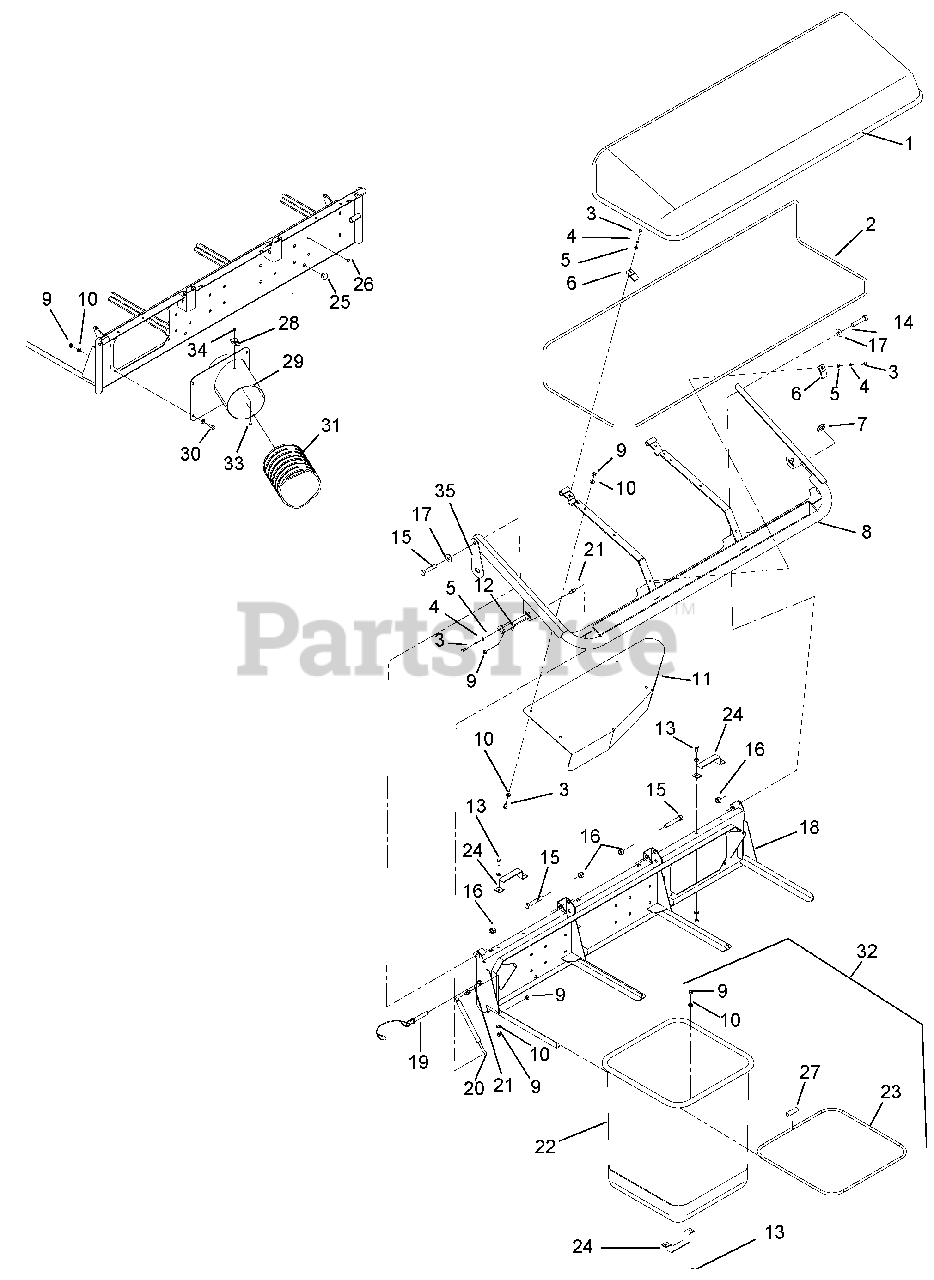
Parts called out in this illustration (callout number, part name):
1	3-Bag Fabric Cover with J-Strip
2	Air Dome Frame .38 Rod
3	Bolt, Hex .25-20 x .75 Grade 5
4	Washer, Locking .25 x .062
5	Washer, Flat Steel .281 x .62 x .065
6	Bracket, Mount Single Hole
7	Hole Plug, Round
8	Cap Support – 3 Bag
9	Nut, .31-18 Nyloc Flange
10	Washer, Flat Steel .344 x .688 x .065
11	3-Bag Deflector
12	Bracket, Gas Cylinder Mount
13	Bolt, Hex .31-18 x .75 Grade 5
14	Bolt, Hex .50-13 x 2.50 Grade 5
15	Bolt, Hex .50-13 x 3.00 Grade 5
16	Nut, Locking Nylon .50-13
17	Washer, Flat Steel .531 x 1.06 x .095 YWZC
18	3-Bag Support Mount
19	Detent Pin with Lanyard 1/2 x 2.50
20	Gas Cylinder
21	Ball Stud
22	Cloth Bag
23	Grass Bag Frame
24	Bag Handle
25	Rubber Bumper
26	Hole Plug 7/16
27	Tube Connector
28	Thumb Latch, A-10 Quick Release
29	Inlet Adapter Tube
30	Bolt, Hex .31-18 x 1.00 Grade 5
31	Hose, Bagger 38"
32	Bag Assembly
33	Screw, Machine 10-24 x .50 Hex Washer Head
34	Nut, Locking Nyloc 10-24 with Insert
35	Pin Adjustment Bracket
